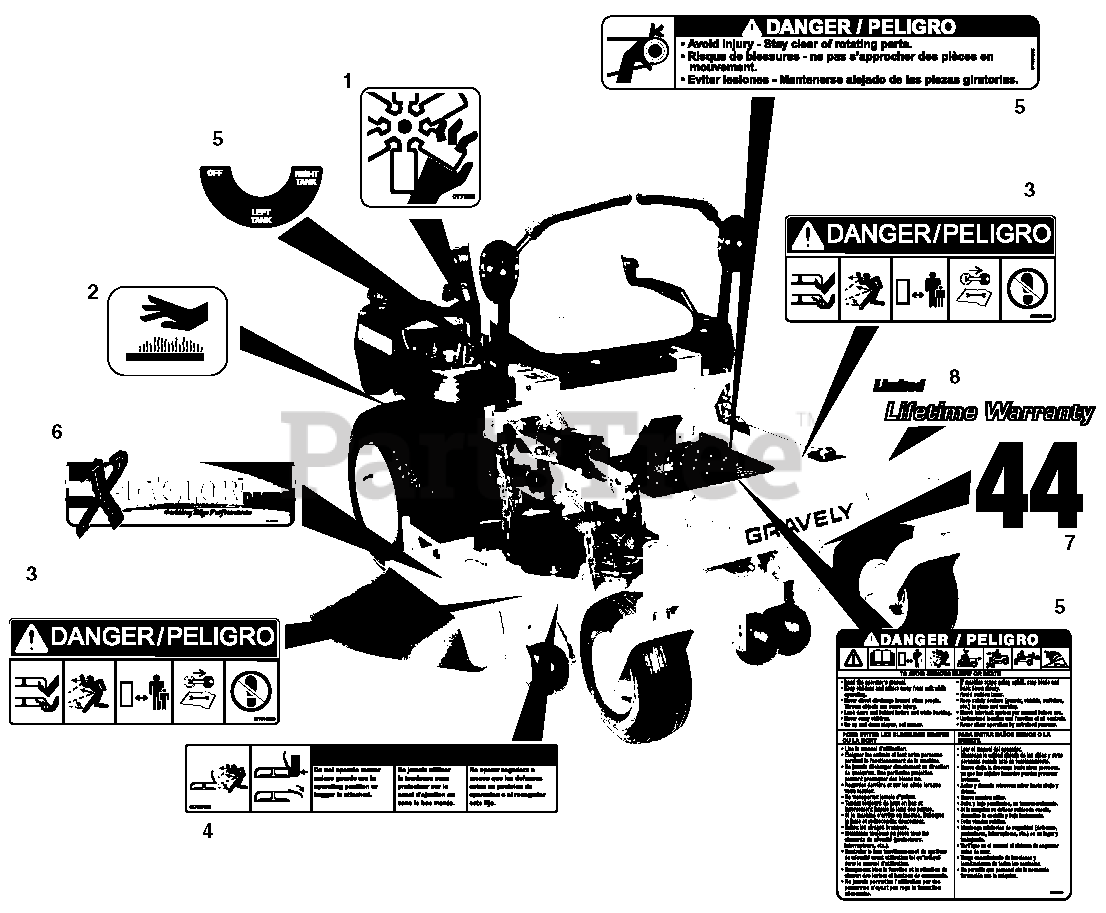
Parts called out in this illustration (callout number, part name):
1	Decal, Danger Fan
2	Decal, Hot Surface
3	Decal, Mower Pan Head Danger
4	Decal, Warning
5	Set, Decal Common Danger/Fuel
6	Decal, X-Factor Deck
7	Decal, 44
8	Decal, Limited Lifetime Warranty
